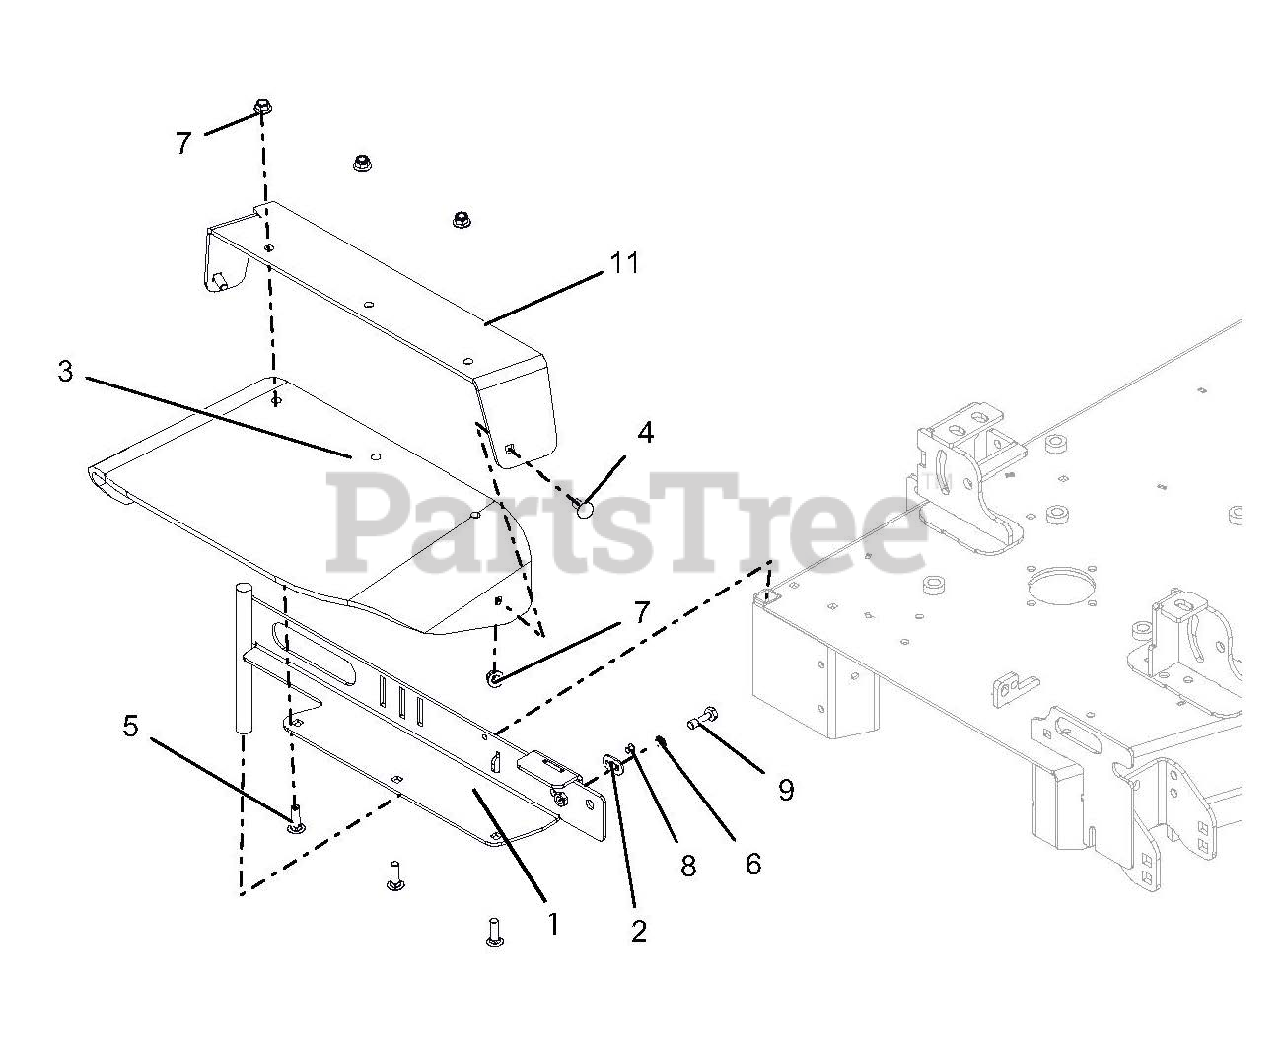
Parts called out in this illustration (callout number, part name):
1	WLDMT, 52" DISCHARGE CHUTE MTG-CE
2	KEEPER, BOLT
3	CHUTE, RUBBER DISCHARGE
4	BLT-RDHDSQNK .38-16X1.00 G5 YWZC
5	BLT-RDHDSQNK .38-16X1.25 G5 YWZC
6	LOCK, WSHR-EXT 0.391 X 0.628 X 0.036 YWZC
7	NUT-LK-NYL-FLG .38-16 YWZC
8	RVT-POP .187x.250 (#64) YWZC
9	BLT-HEX .38-16X1.25 GR5 CAP .37
11	DISCHARGE CHUTE SUPPORT W/SAFETY DECAL
